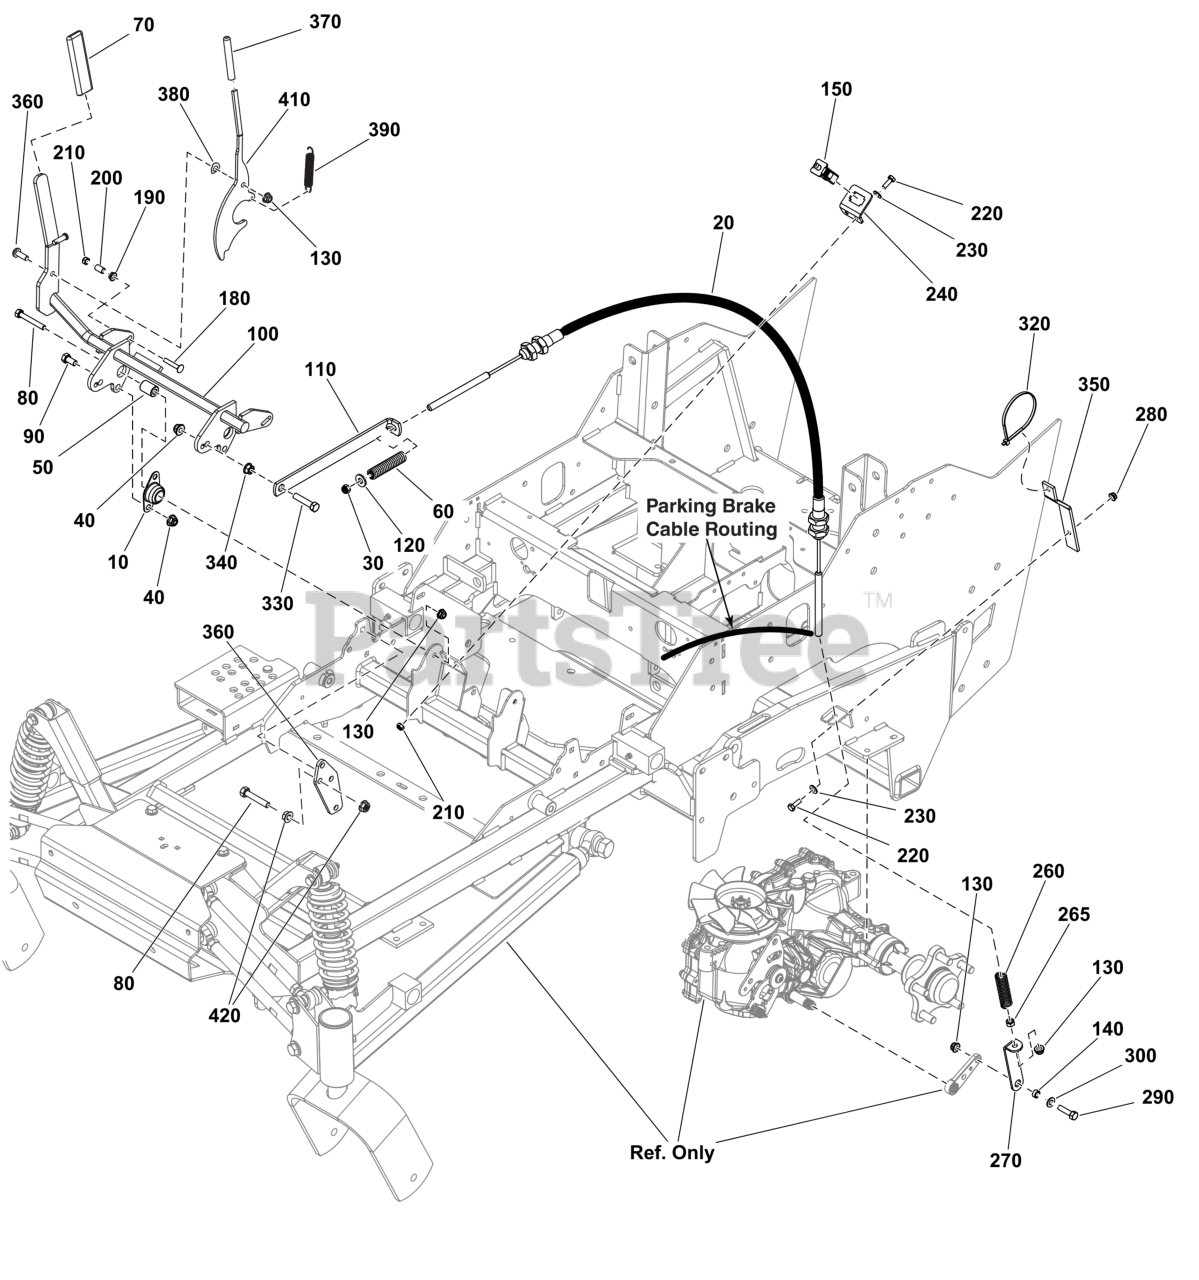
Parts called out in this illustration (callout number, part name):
10	BEARING, BRONZE FLANG
20	CABLE,PARKING BRAKE
30	NUT, 5/16-24 HEX NYLO
40	NUT, 3/8-16 HEX NYLOCK
50	SPACER, .32 X .75 X 1
60	SPRING, CONTROL ROD
70	GRIP, FOAM, 1/4" X 1
80	BOLT, 5/16-18 X 1-3/4
90	BOLT, 3/8-16 X 3/4" G
110	LATCH, Parking Brake
130	NUT
140	SPACER, .33 X .50X.25
150	SWITCH, DP NO/NC SNAP
180	BOLT, 1/4-20 X 1.5
210	NUT, 1/4-20 HEX NYLON
220	BOLT, 1/4-20 X 3/4" G
230	WASHER
260	SPRING, COMPRESSION,
265	NUT, 5/16-18 HEX
270	LINK, LOWER BRAKE
300	WASHER
320	TIE WRAP, 11" Long
330	BOLT, 3/8-16 X 1-3/4"
340	NUT, 3/8-16 HEX SERRA
350	BRACKET
360	SCREW, TRUSS HD TORX
370	COVER, VINYL HANDLE
380	WASHER,WAVE,M10
390	SPRING, EXTENSION
420	NUT, 5/16-18 HEX SERR
